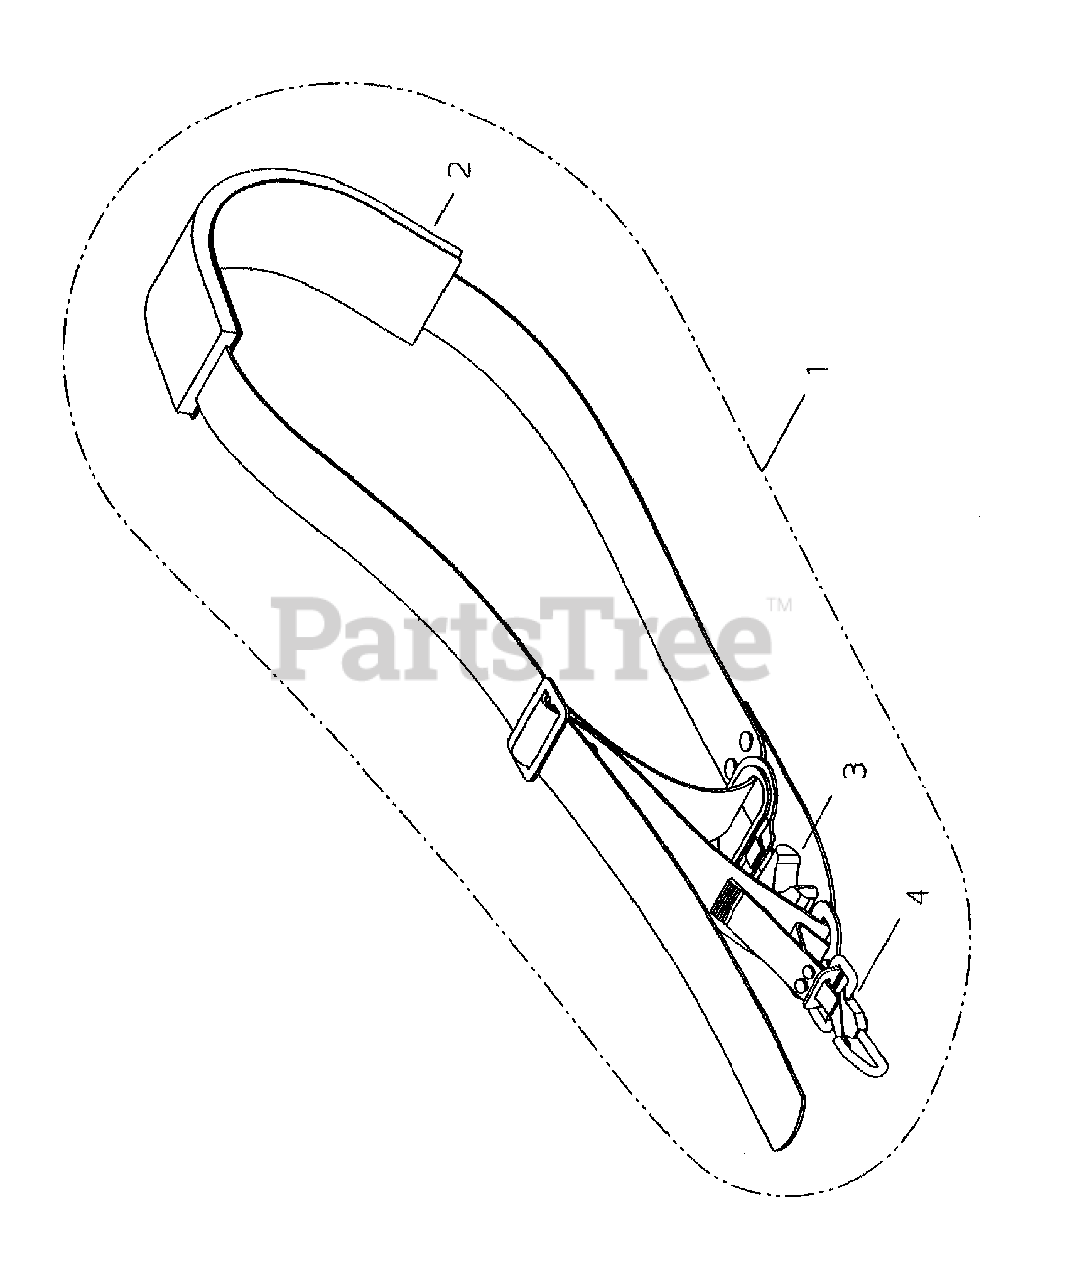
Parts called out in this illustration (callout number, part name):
1	HARNESS ASSY
2	PAD
3	CUSHION
4	HOOK
